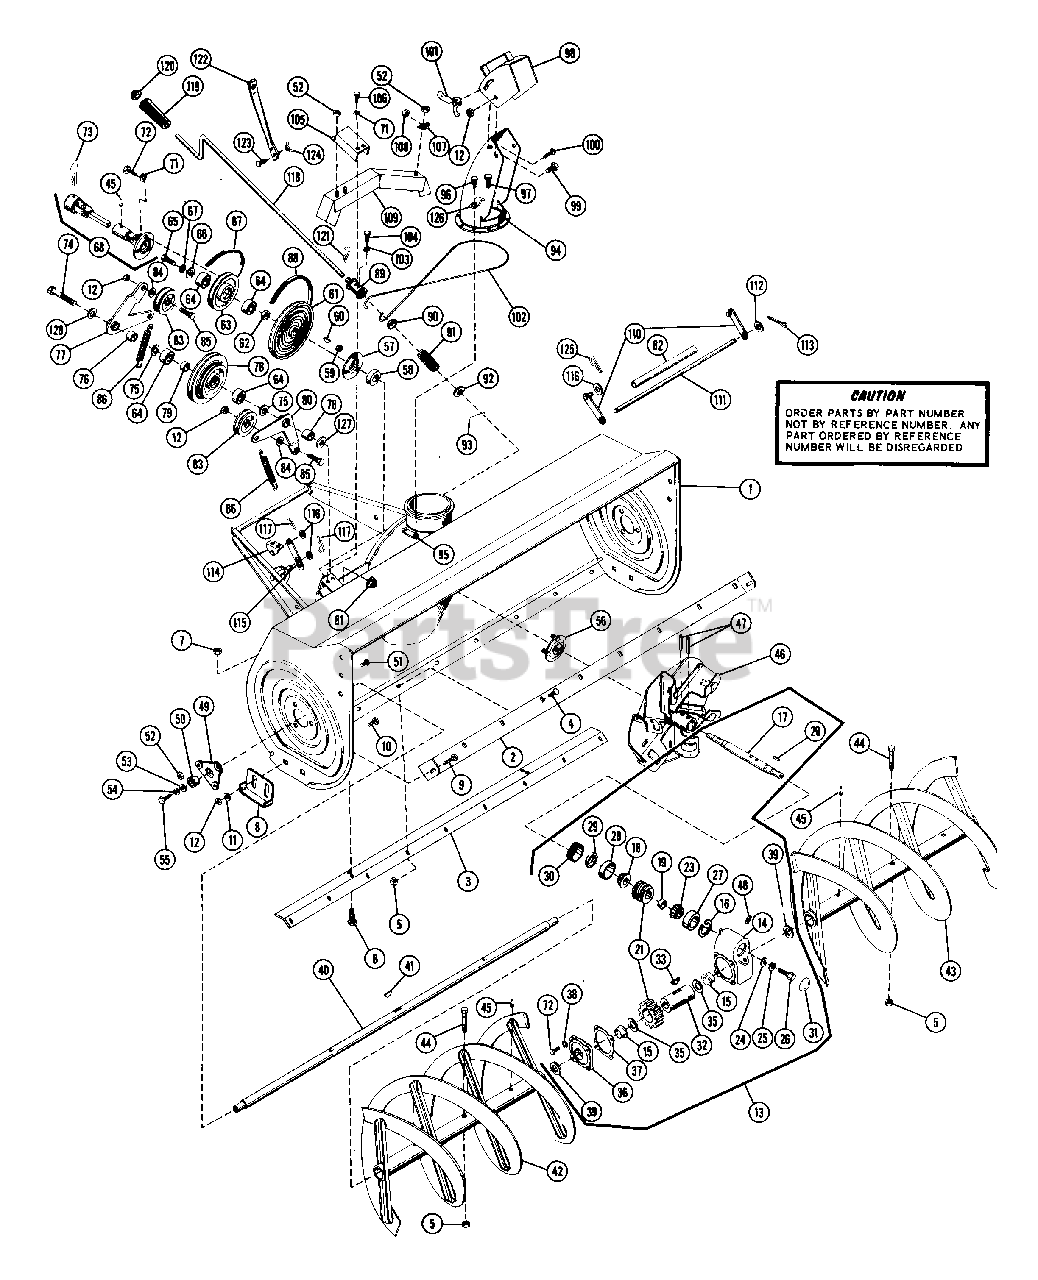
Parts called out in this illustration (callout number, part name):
1	BLOWER HOUSING ASSEMBLY
2	SCRAPER BLADE
3	SCRAPER BLADE BRACE
4	BLT-RDHDSQNK .31-18X.75 GR5 PL
5	NUT-LK .312-18 GR A PL
6	BLT-HEX .38-16X.75 PL GR5
7	NUT-LK TOP .375-16 GR C YWZC
8	SKID SHOE
9	BLT-RDHDSQSHNK .38-16X1.00 PL
10	BLT-RDHDSQNK .38-16X.75 SHT PL
11	WSHR-FL-STL .38X.875X.083 PL
12	NUT-LK-CTR .375-16 GR A PL
13	GEAR CASE - CAST IRON
14	GEAR CASE - CAST IRON
15	BSHG-FLG .683X1.87X1.68X2.250
16	RG-RTNG INT 1.781 HSG X.062
17	WORM SHAFT
18	BRG-CONE 1.0X.58
19	BEARING SPACER 1.032X1.25X1.78
20	KEY-SQ .188X1.0X.188 SAE 8630
21	WORM & GEAR ASSEMBLY
22	BSHG, SPCR .755X1.12X.50 PM
23	BRG-CONE .750X.61
24	WSHR-FL-STL .328X1.0X.094
25	WSHR-LK .312X.097 PL HVY
26	BLT-HEX .31-18X.75 PL GR2
27	BRG-CUP 1.781X.475
28	BRG-CUP1.980X.420
29	SEAL 1.125X1.375X.125
30	ADJUSTMENT PLUG
31	DUST CAP
32	GEAR CASE SHAFT
33	KEY-FTHR .25X.875X.312
35	WSHR-FL-STL 1.625X2.500X.012
36	GEAR CASE COVER
38	WSHR-LK-EXT. 250 ID
39	SEAL 1.625X2.125X.250
40	RAKE SHAFT
41	KEY-WDRF .25X.875X.375 SAE A
42	RAKE, RIGHT-48(1.12ID X 15.75)
43	RAKE, LEFT-48"(1.12ID X 15.75)
44	SHEAR BOLT & NUT ASSEMBLY
45	SPIN DRIVE ZERK FITTING
47	PIN-ROLL .313X1.75
48	PIPE PLUG
49	BEARING SUPPORT
50	BSHG-FLG 1.000X1.12X.62X1.50BR
51	SCR-SLTR-SERNK .25-20X.62 PL
52	NUT-LK-FLG .250-20 PL
53	WSHR-FL-STL .511X1.441X.125 PL
54	WSHR-LK .500X.151 HVY PL
55	BLT-HEX .50-13X1.00 PL GR2
56	BEARING FLANGE
57	BEARING FLANGE
58	BRG-BALL 1.0X2.0X.56
59	NUT-LK-CTR .250-20 PL
60	KEY-WDRF .188X.875X.375 SAE11
61	PLY-V 10.00 X .88 W/KEY SALEM
62	SPACER .906X1.125X.453
64	BRG-BALL .751X1.78X.61
65	BLT-HEX .38-16X1.00 PL
66	WSHR-FL-STL .438X1.0X.083 PL
67	WSHR-LK .375X.094 MED PL
68	UNIVERSAL SHAFT ASSEMBLY
71	WSHR-LK .250X.077 HVY PL
72	BLT-HEX .25-20X.75 PL GR2
73	PIN-HAIR INT .18X1.18X3.25 PL
74	BLT-HEX .75-10X5.00 GR2
75	WSHR-FL-STL .755X1.375X.062 PL
76	BSHG-SLV .750X1.125X1.062
77	IDLER ARM
79	SPACER .781X1.000X.547
80	IDLER ARM
81	NUT-LK-FLG .75-10 GR F PL
82	TUBE .725 X .875 X 14.00
83	IDLER-FLAT 3.00 X .38 CLK.&CAP
84	WSHR-FL-STL .406X.875X.135
85	BLT-HEX .38-16X1.25 PL GR 2
86	SG-TENS 6.0 FREE LENGTH
87	V-BELT, HA-RAW EDGE
88	V-BELT, 4L-RAW EDGE
90	SPHERICAL WASHER
91	SG-COMP .054X.75X1.6
92	WSHR-FL-STL .641X1.250X.188
93	PIN-COTR .12 X 1.25 PL
94	DISCHARGE CHUTE
95	CHUTE CLAMP
96	SCR-TAP 10-24X.375 HWH PL TR
97	SCR-TAP 10-24X.75 HWH PL TR
98	SERVICE DEFLECTOR ASSM
99	BLT-HEX .38-16X.75 PL GR2
100	BLT-RDHDSQNK .38-16X.75 SHT PL
101	WING NUT
103	WSHR-LK .313X.062
104	BLT-SCRHFWH .25-20X.62 PL
106	BLT-HEX .25-20X.50 PL GR2
108	NUT-FLG. .312-18 PL
109	BELT GUARD
110	LIFT STRAP
112	WSHR-FL-STL .688X1.75X.134PL
113	PIN-COTR .12 X 1.25 PL
114	LIMITING POST
115	LIMITING ARM
116	WSHR-FL-STL .531X1.062X.095 PL
117	PIN-HAIR INT .09X.188 PL
118	CHUTE CRANK
120	CAP, 3/8 ROD YWZC
121	PIN-HAIR INT .08X.38X1.42 YWZC
122	SUPPORT
123	BLT-RDHDSQNK .38-16X1.0 GR5PL
124	NUT-WING .375-16 ZCC
125	PIN-HAIR INT .14X.4X2.75
126	CABLE CLAMP
127	WSHR-HDND-THRST .755X1.40X.062
128	WSHR-FL-STL .811X1.25X.025
